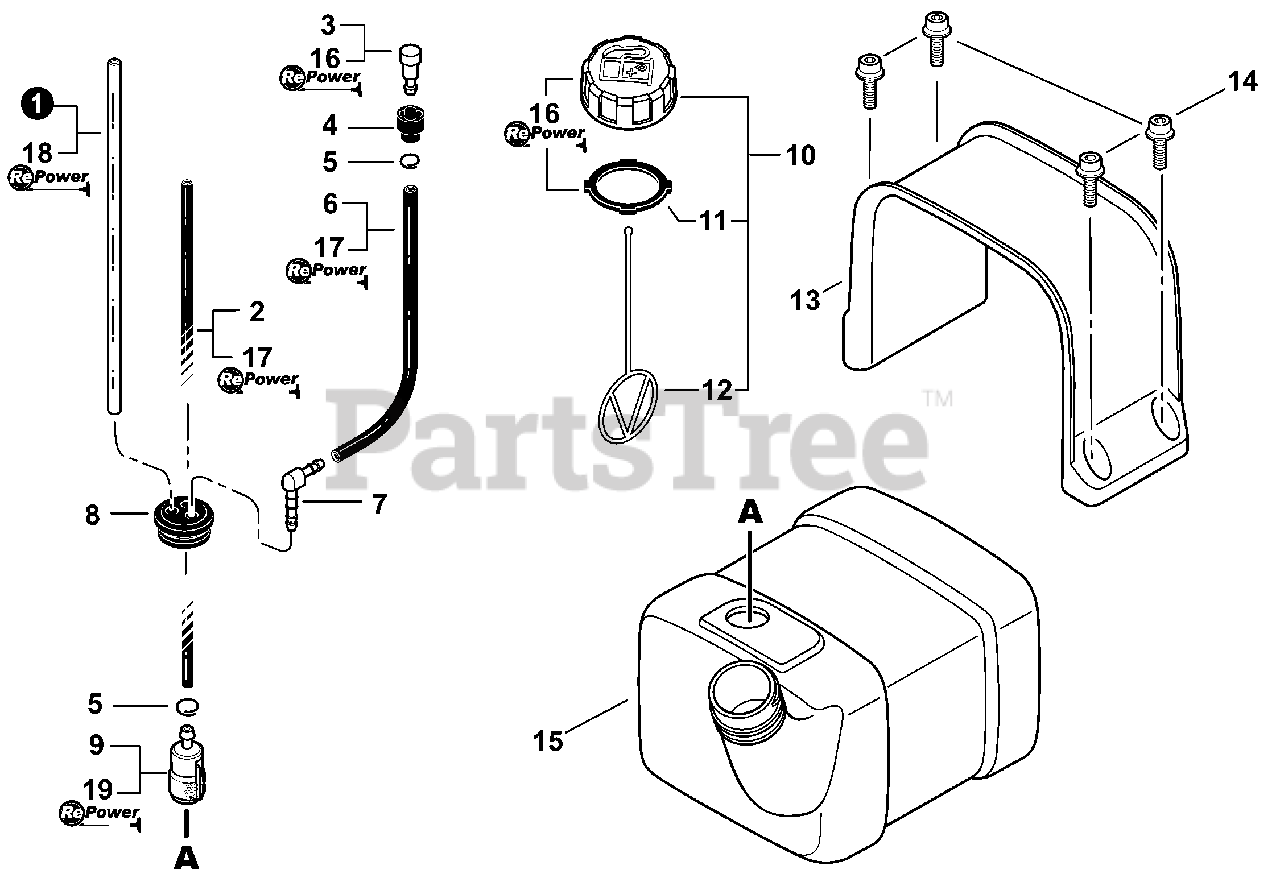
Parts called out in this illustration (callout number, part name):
1	PIPE, FUEL RETURN 3×6×145
2	PIPE, FUEL 3×6×230
3	VENT ASSY
4	HOLDER, VENT
5	CLIP Ø6.5 MM
6	PIPE, VENT 3×6×145 MM
7	CONNECTOR, PIPE
8	GROMMET, FUEL
9	FILTER, FUEL
10	CAP ASSY, FUEL
11	GASKET, FUEL CAP
12	CONNECTOR, CAP L= 100 MM
13	BRACKET, FUEL TANK
14	BOLT 5×16
15	TANK, FUEL
16	CAP/VENT KIT - REPOWER
17	BULK PIPE - 3×6 MM BLACK (4 PIECES×2 M)
18	BULK PIPE - 3×6 MM CLEAR (4 PIECES×2 M)
19	TUNE-UP KIT - REPOWER
